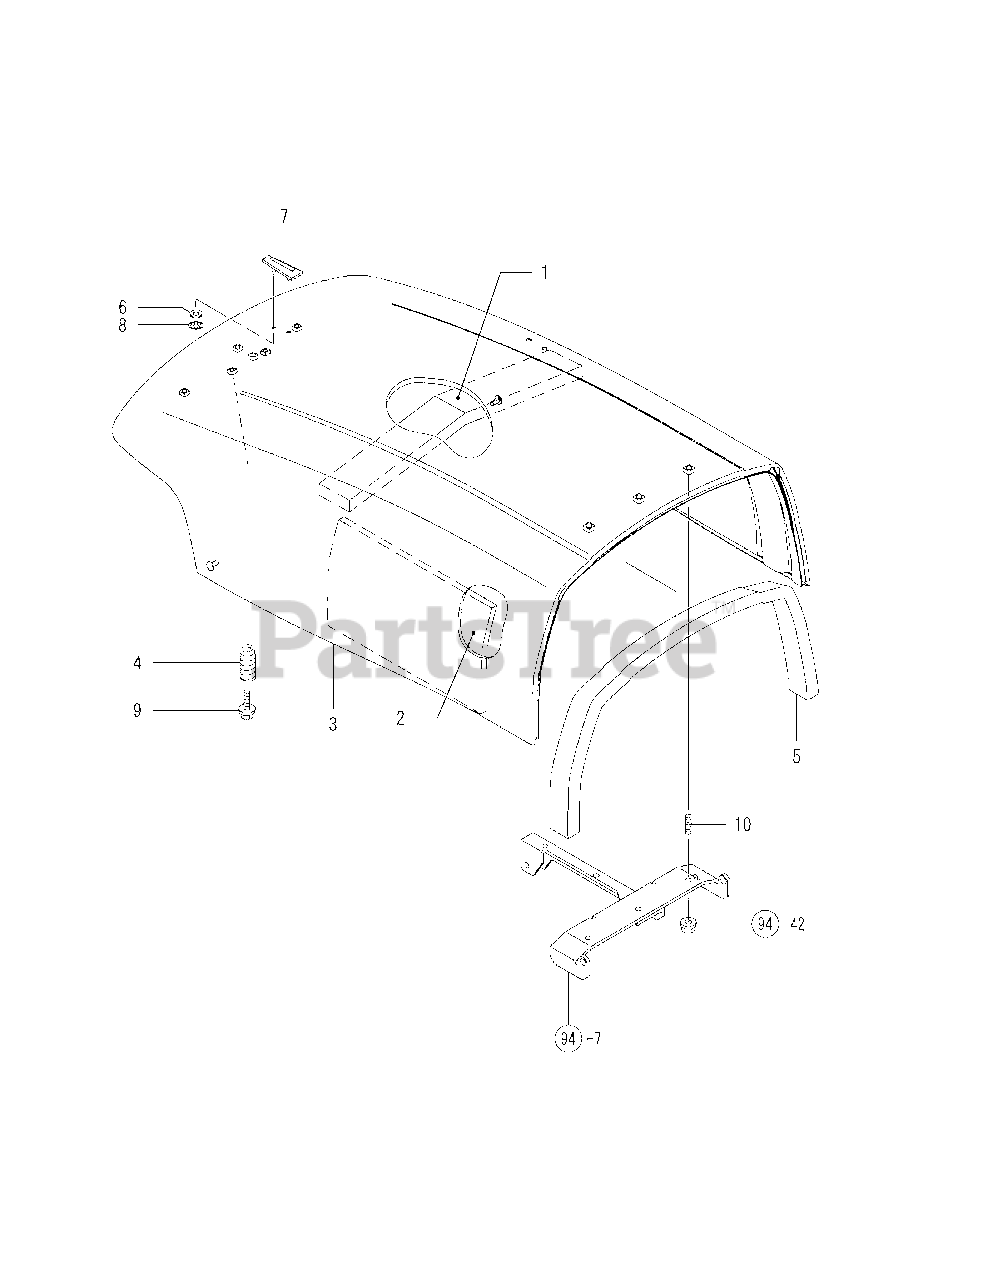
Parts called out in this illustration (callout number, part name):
1	URETHANE, HOOD UPPER
2	URETHANE, HOOD UPPER
8	NUT M5, SPEED
9	BOLT M 6X 16 PLATED
10	STUD M 8 14 PLATED
